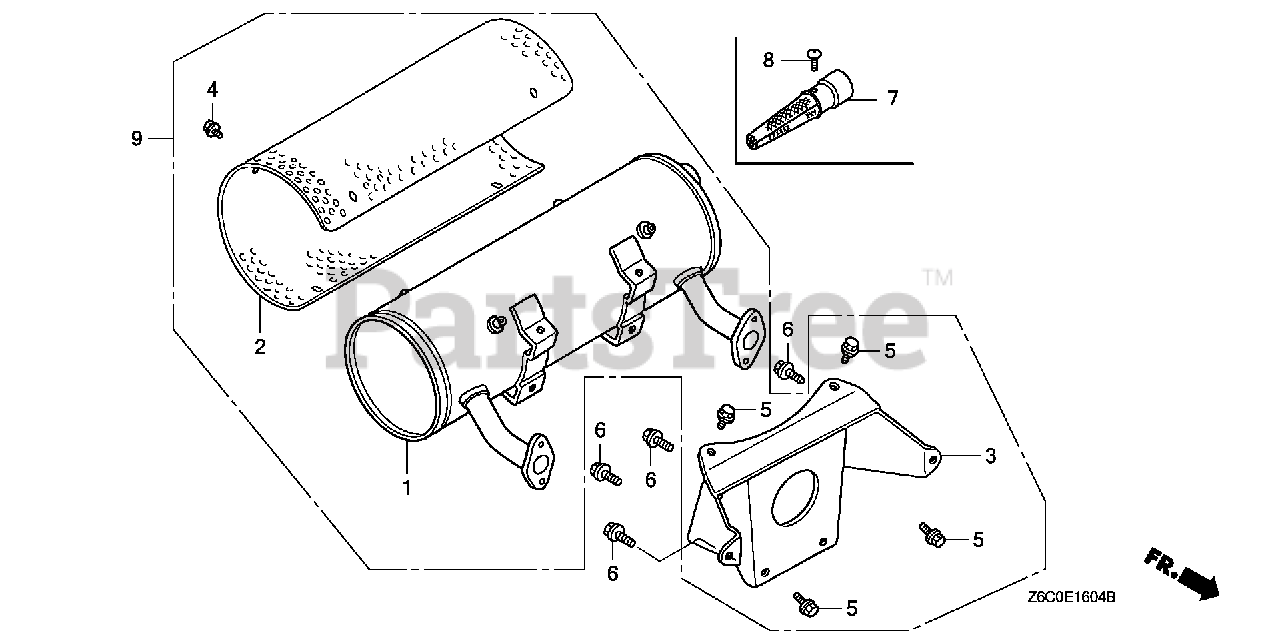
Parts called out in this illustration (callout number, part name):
1	MUFFLER ASSY. (HIGH-L) (FUTABA) (SILVER MUFFLER)
1	MUFFLER COMP. (HIGH-L) (FUTABA) (SILVER MUFFLER) (FOR SILVER MUFFLER)
2	PROTECTOR, MUFFLER (HIGH) (FUTABA)
2	PROTECTOR, MUFFLER (HIGH)(NELSON) (FOR BLACK MUFFLER)
3	STAY, MUFFLER (HIGH-FUTABA) (FOR SILVER MUFFLER)
3	STAY, MUFFLER (HIGH-NELSON) (FOR BLACK MUFFLER)
4	BOLT, FLANGE (6X8)
5	BOLT, FLANGE (8X14)
6	BOLT, FLANGE (8X20)
7	ARRESTER KIT (HIGH)
7	ARRESTER, SPARK (FOR SILVER MUFFLER)
8	SCREW, TAPPING (5X8) (FOR SILVER MUFFLER)
9	MUFFLER ASSY. (HIGH-L) (FUTABA) (SILVER MUFFLER)
